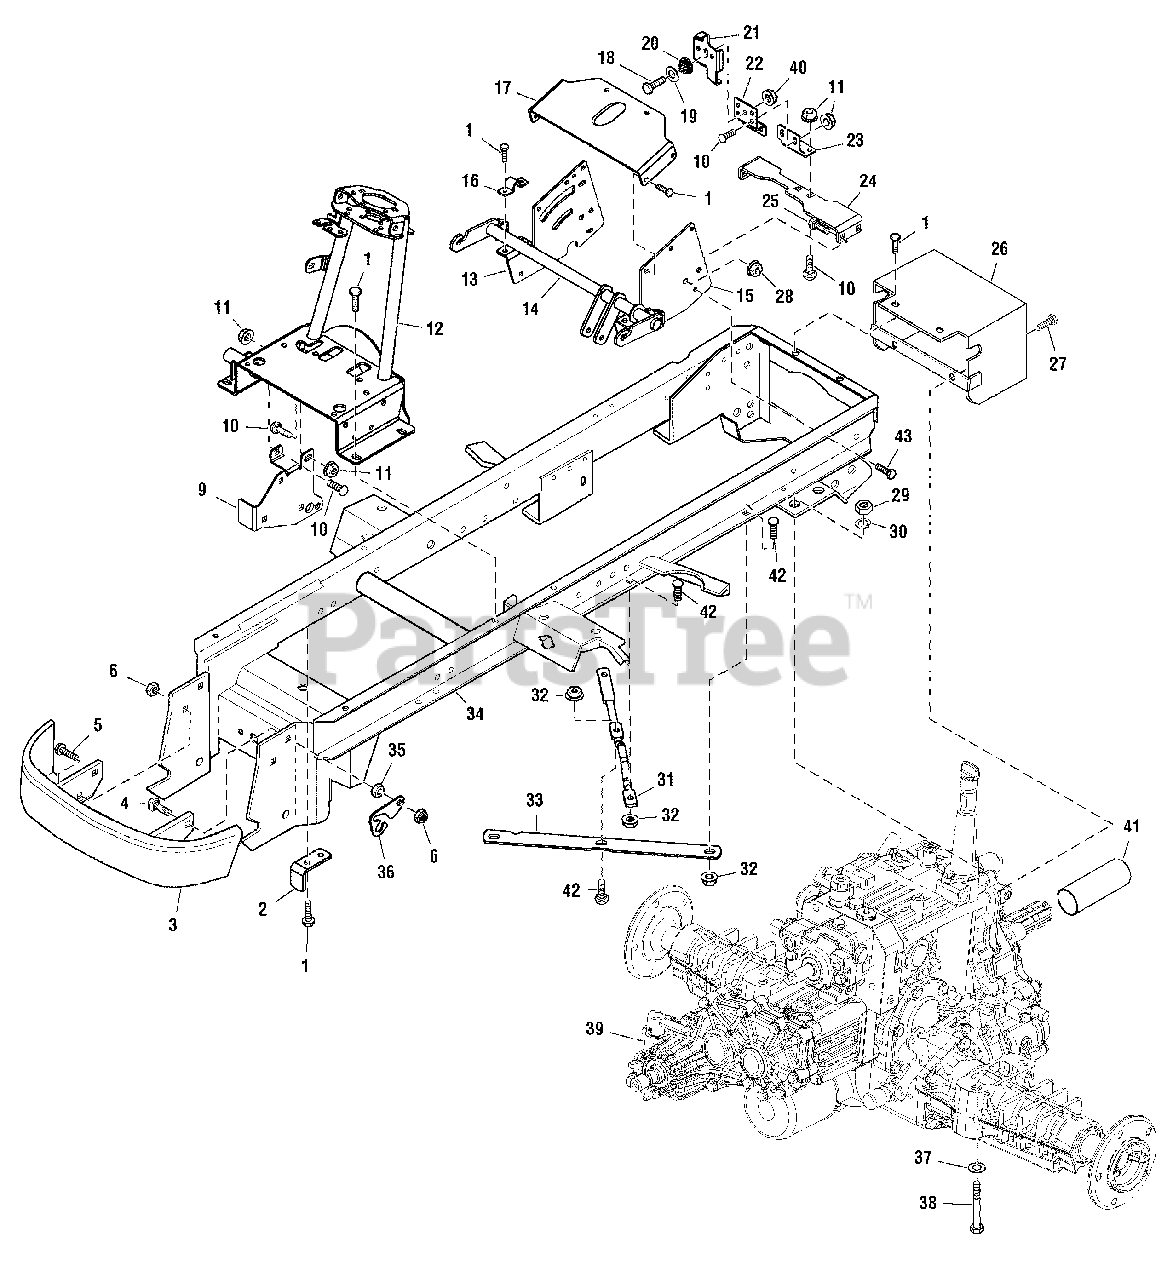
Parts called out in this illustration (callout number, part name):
1	CAPSCREW, Hex, Washer Head, Taptite, 5/16-18 x 3/4, Black
2	BRACKET, Upstop
3	BUMPER & BRACKETS ASSEMBLY
4	BOLT, Carriage, Short Neck, 1/2-13 x 2
5	CAPSCREW, Hex, 1/2-13 x 1-1/2
6	NUT, Hex, Lock ESNA, 1/2-13
9	SUPPORT, Control Valve
10	CARRIAGE BOLT, 5/16-18 x 3/4, Black
11	NUT, Hex, KEPS 5/16-18, Black
12	TOWER ASSEMBLY
13	SUPPORT, Seat Support, R.H.
14	SHAFT ASSEMBLY
15	SUPPORT, Seat Support, L.H.
16	STRAP
17	SUPPORT, Seat Deck
18	CAPSCREW, Hex Head, 5/16-18 x 1
19	WASHER, 5/16
20	SPRING, Tension
21	BRACKET, Free Wheel
22	SUPPORT, Free Wheel Latch
23	SUPPORT, Dump Valve
24	BRACKET, Torque Strap
25	CARRIAGE BOLT, 3/8-16 x 1 Black
26	SHIELD & BRACKET ASSEMBLY
27	CAPSCREW, Hex Head, M12-1.75 x 25MM
28	NUT, Hex, Flange ESNA, 3/8-16, Black
29	NUT, Hex Flange Center Lock, M12-1.25
30	LOCKWASHER, Spring, 1/2
32	NUT, Hex, KEPS, Conical Washer, 3/8-16
33	BRACE, Cross
34	FRAME ASSEMBLY
35	NUT, Hex Jam, 1/2-13
36	LOCK, Hood
37	WASHER, 1/2
38	CAPSCREW, Hex Head, M12-1.25 x 100MM,
39	TRANSMISSION ASSEMBLY, 4WD, K92C, W/540
40	NUT, Hex, Flange ESNA, 5/16-18, Black
41	COVER, PTO Shaft
42	BOLT, 3/8-16 x 1 1/4
43	SCREW, Hex, Washer 5/16-18 x 1.000
